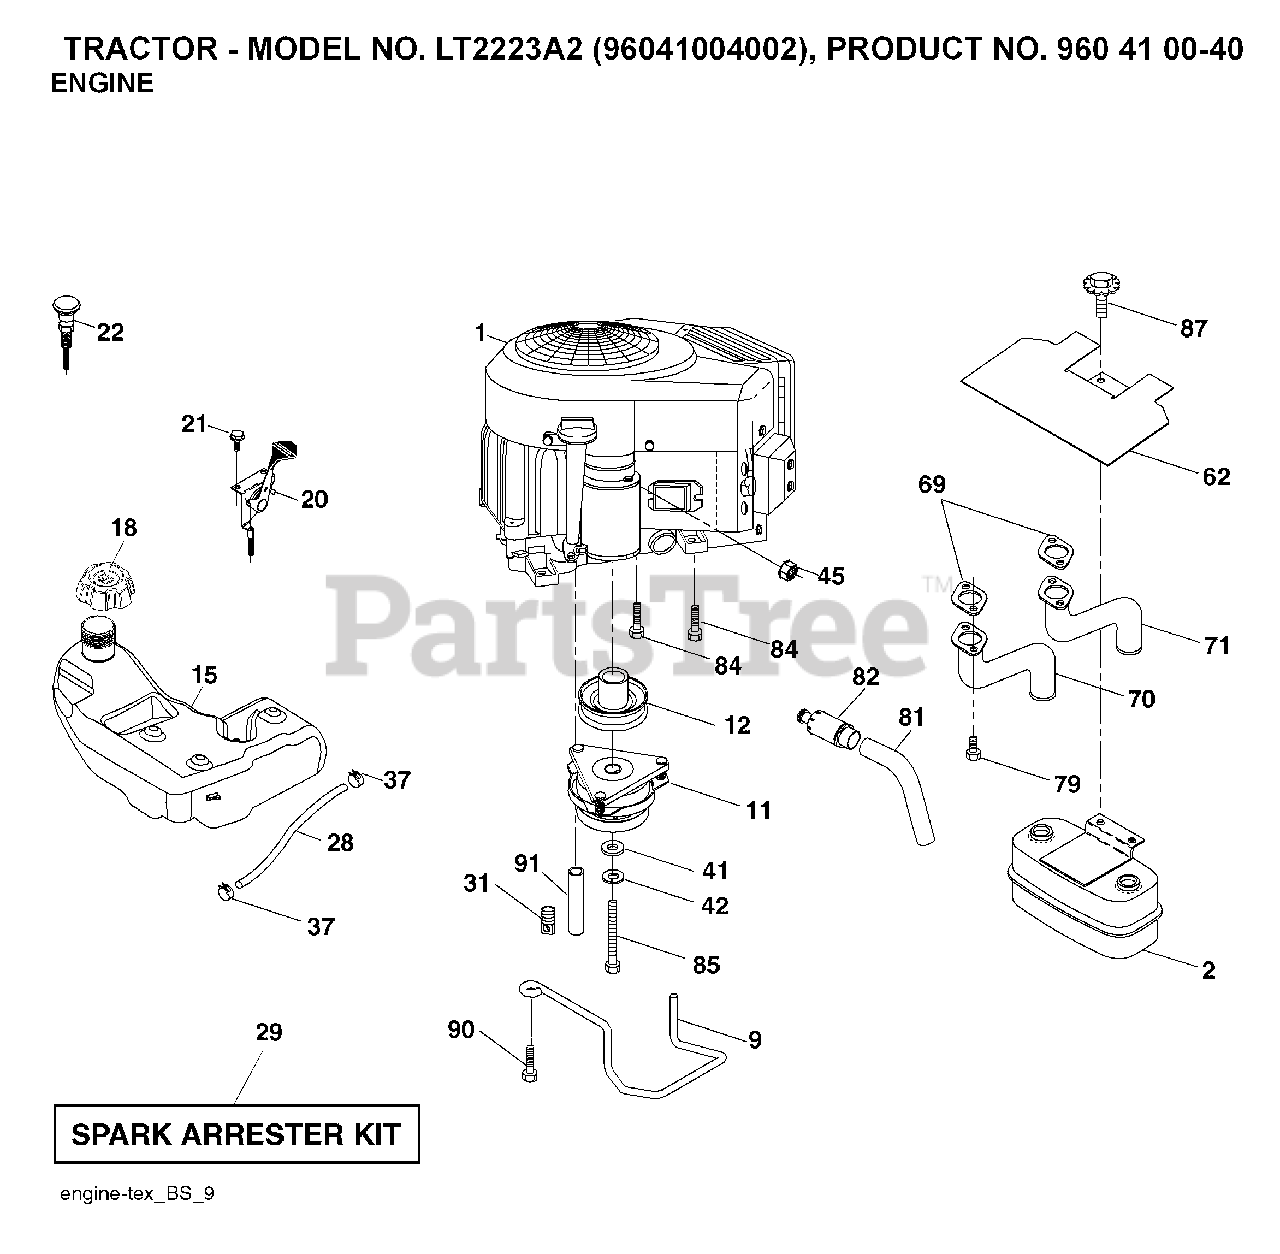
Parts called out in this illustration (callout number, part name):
2	MUFFLER.TWIN.CYL.LOW.TONE
9	KEEPER.BELT.ENGINE.4.2
11	CLUTCH ELECTRIC
12	PULLEY ENGINE
15	TANK.FUEL.4GAL
18	CAP.ASM.FUEL.TANK.3"BL
20	THROTTLE CABLE
21	SCREW.#10 X 0.750.BOS THREAD
22	CONTROL CHOKE
29	ARRESTER SPARK (OPTIONAL)
31	PUSH CLIP
37	HOSE CLAMP
42	LOCKWASHER
45	NUT
62	RP SHIELD HEAT MUFFLER
69	GASKET.MUFFLER
70	TUBE MANIFOLD LH
71	EXHAUST TUBE RH
79	SCREW.SOCKET.HEAD.5/16-18
81	TUBE, DRAIN OIL ASM.
82	PLUG DRAIN OIL EASY
84	SCREW.3/8-16
85	BOLT HEX 7/16-20 X 3.75 GR. 5
87	BOLT.5/16-18UNCX1.W/SEMS.BLK
90	SCREW 3/8-16X1
91	BUSHING.1.375OD
